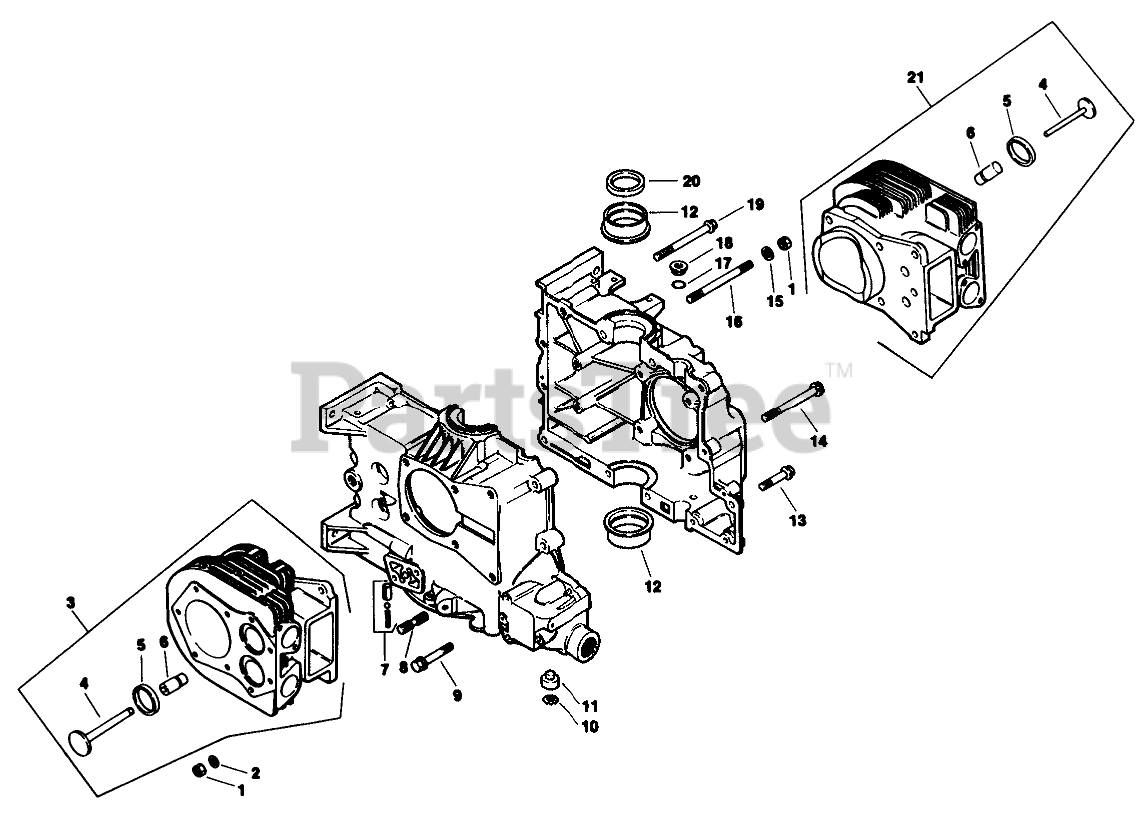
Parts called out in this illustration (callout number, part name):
1	Nut
2	Washer-Flat
3	Kit-#1 Cylinder Barrel (Incl. Ref. #4-6)
4	Valve-Exhaust
5	Insert
6	Guide-Valve
7	Kit-Oil Relief
9	Screw-Hex Flange
10	Ring-Retaining
11	Shaft-Governor
12	Bearing-Sleeve
12	Bearing-Sleeve .010"
12	Bearing-Sleeve .020"
13	Screw-Hex Flange
14	Screw-Hex Flange
15	Washer-Flat
16	Stud
19	Screw-Hex Flange
20	Seal-ReAR Oil
21	Kit-#2 Cylinder Barrel (Incl. Ref. #4-6)
